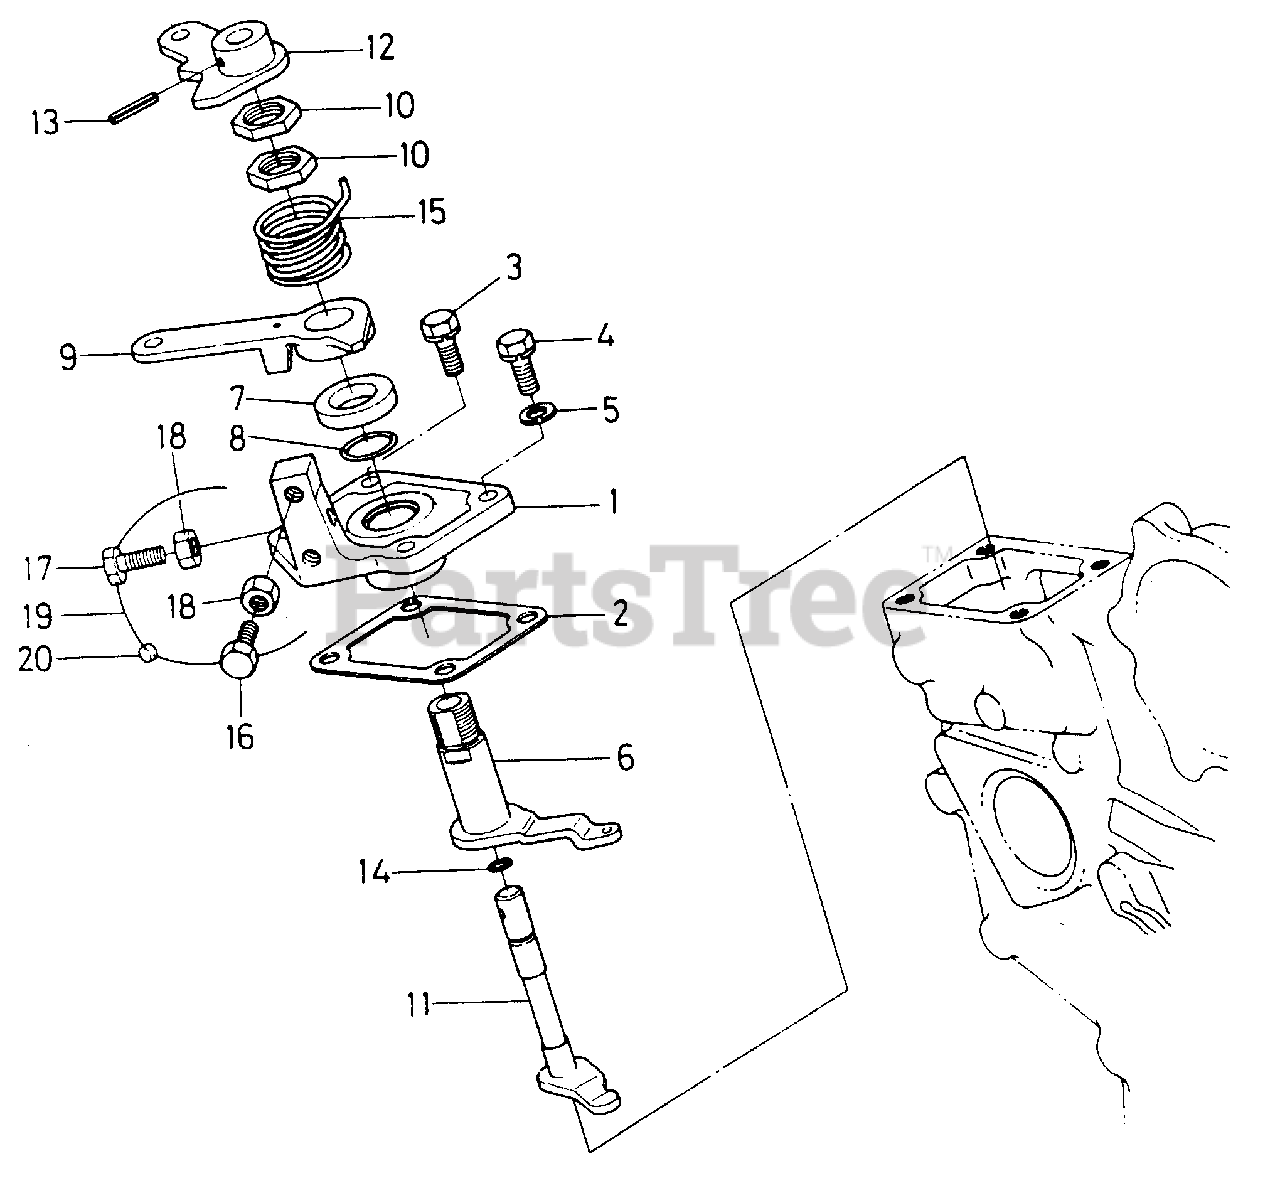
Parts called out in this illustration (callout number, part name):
1	Plate, Speed Control
2	Plate, Speed Control
3	Bolt, M6 X 18-8.8 w/Washer
4	Bolt, M6 X 18-8.8
6	Lever, Governor
8	O-Ring, 5/8 X 3/4
9	Lever, Speed Control
12	Lever, Engine Stop
13	Pin, 3 X 10MM Pln Slt-Spr
14	O-Ring, 5/32 X 9/32
15	Spring, Return
18	Nut, M6 Znd Class 8
